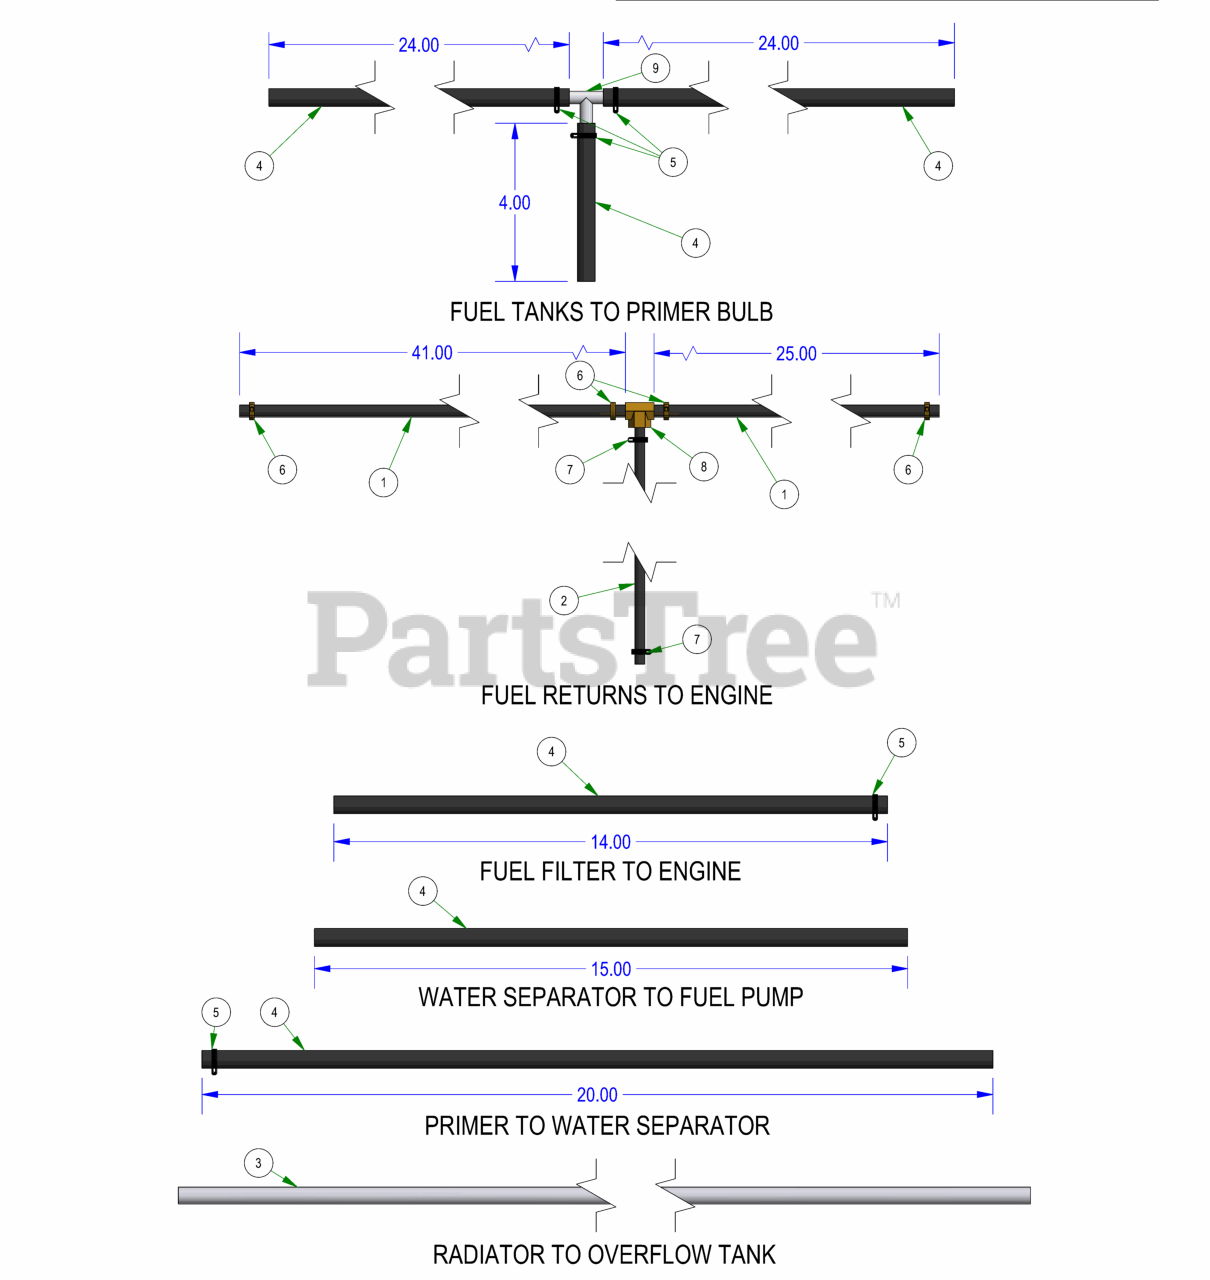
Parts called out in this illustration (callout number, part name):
1	1/4" Fuel Line Hose
2	3/16 Fuel Line
3	5/16 Clear Hose
4	5/16" fuel line hose
5	5/16 Fuel Line Clamp
6	1/4 Fuel Hose Clamp
7	3/16 Vinyl Clamp
8	Brass fuel line T
9	5/16 x 5/16 x 1/4 Fuel Line T
